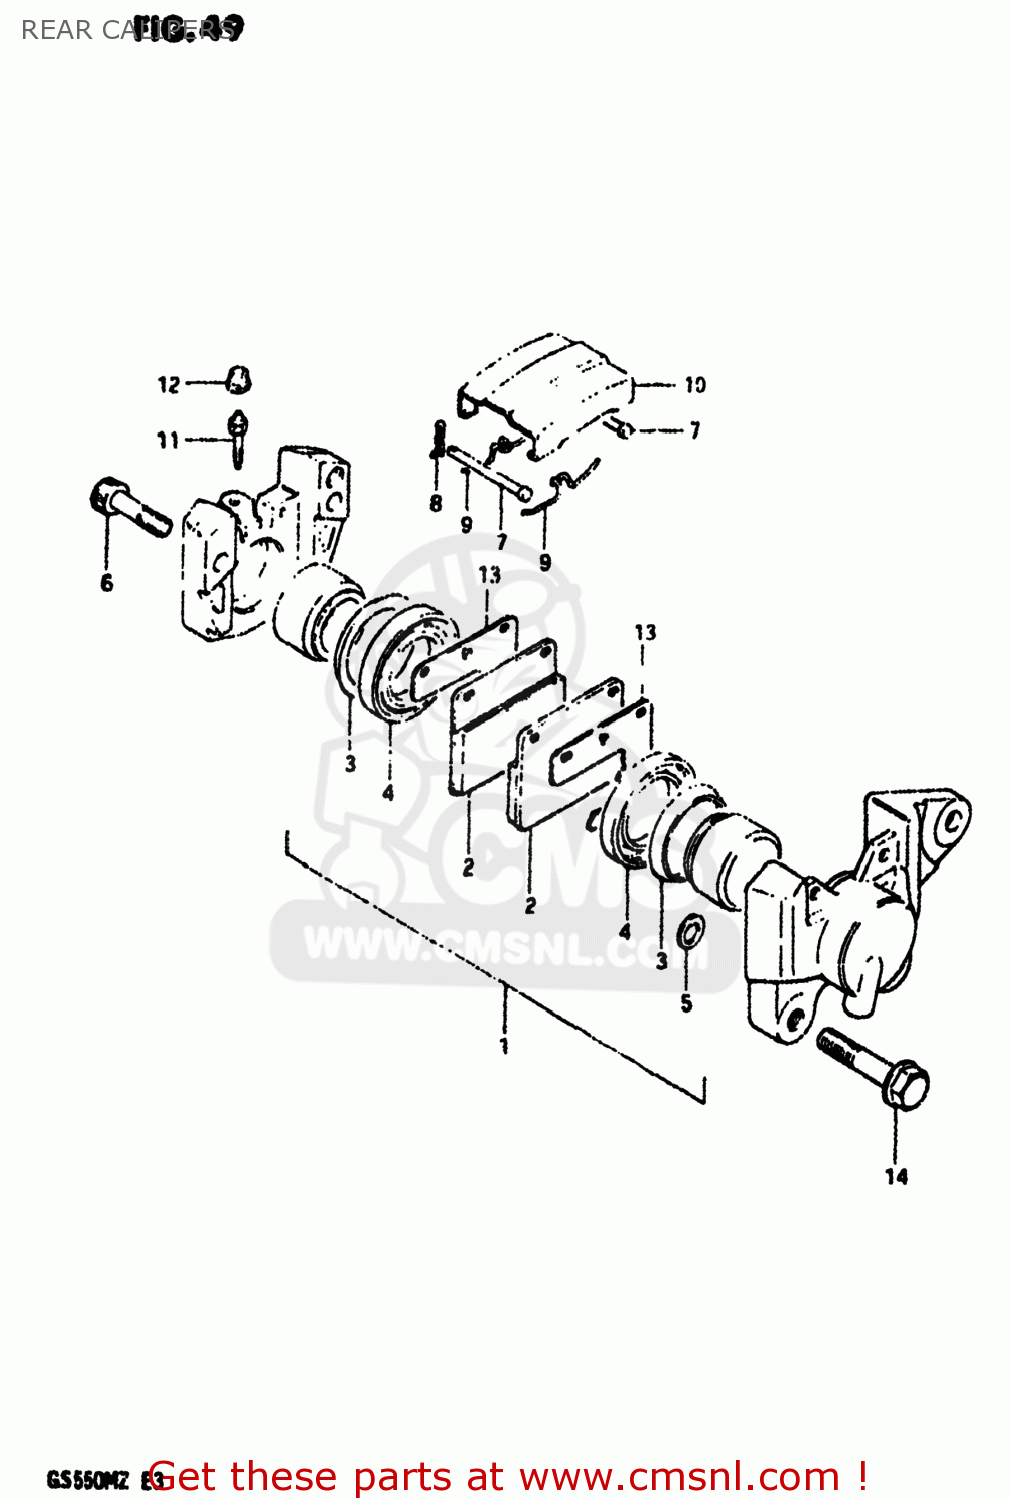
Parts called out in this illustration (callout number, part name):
1	PISTON SET
2	PAD,BRAKE
3	SEAL,PISTON
4	BOOT,PISTON
5	SEAL,JOINT
6	BOLT,CALIPER HOUSING
7	PIN,PAD
8	CLIP,PAD PIN
9	SPRING
10	COVER,DUST
11	BLEEDER
12	CAP,BREATHER
13	SHIM,RR CALIPER
14	BOLT
